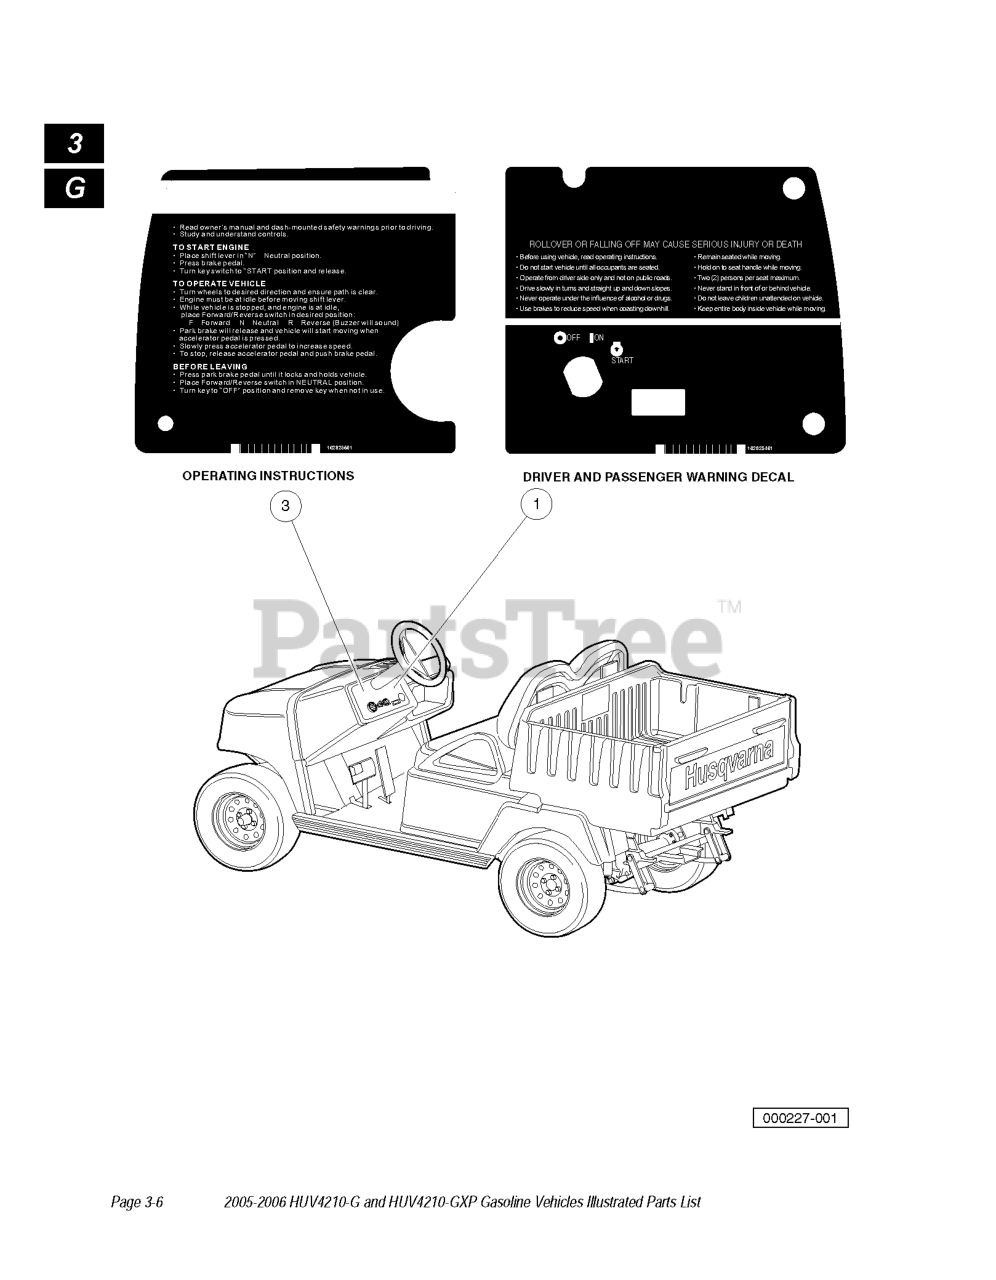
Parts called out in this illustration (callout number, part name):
1	DECAL WARN, IP, G
2	DECAL, WARN, IP, G W12
3	DECAL, OPER INS, IP, H2X2 GAS
